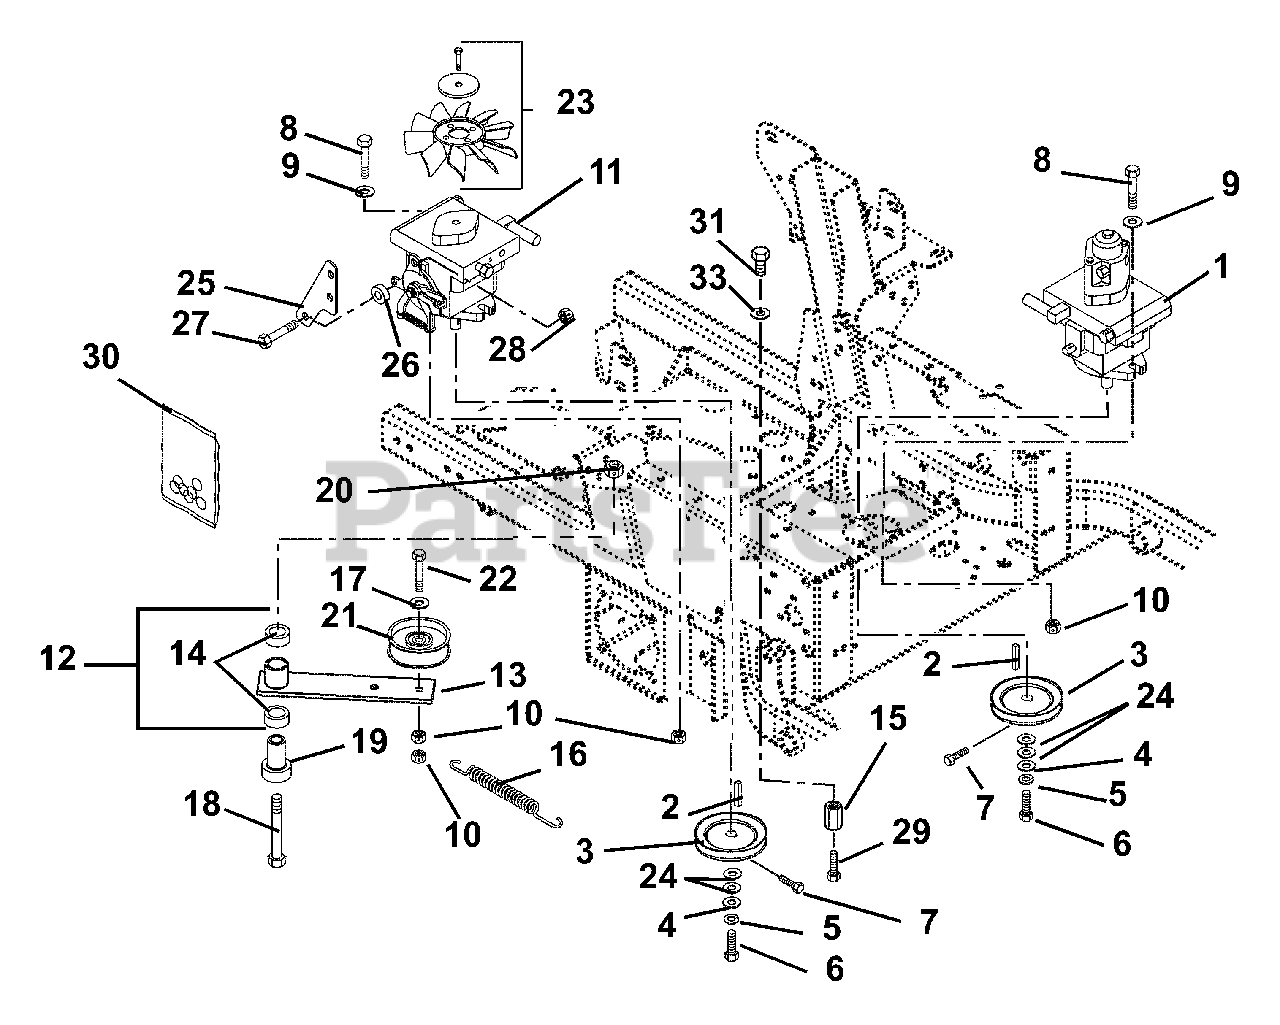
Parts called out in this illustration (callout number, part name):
1	PUMP,10CC DISP,W/AUX,W/REV RTN
2	KEY-STR 5MMX25MMX5MM
3	SHEAVE, PUMP .592 X 4.345
4	WSHR-FL-STL .281X1.000X.063
5	@WSHR-LK .25X.062 REG YWZC
6	BLT-HEX M6 X 1.0X12 YWZC
7	@BLT-HEX .25-20X.50 GR5 YWZC
8	@BLT-HEX .38-16X1.25 GR5 YWZC
9	WSHR-FL-STL .390X.75X.125 YWZC
10	@NUT-LK-TOP-FLG .38-16 YWZC
11	PUMP, BDP-10A-441 (THRU SHAFT)
12	ASSEMBLY,IDLER ARM GRD.DRIVE
13	WMT, IDLER ARM GROUND DRIVE
14	BRG, 1.00 X 1.12 X .75
15	NUT COUPLING .375-16X1.75
16	SPRING, EXTENSION
17	WSHR-FL-STL .390X.75X.125 YWZC
18	@BLT-HEX .50-13X3.50 GR5 YWZC
19	BEARING, PEDESTAL
20	@NUT-LK-TOP-FLG .50-13 YWZC
21	IDLER, FLAT 4.00X1.06
22	@BLT-HEX .38-16X2.25 GR5 YWZC
23	FAN, COOLING
24	@WSHR-FL-STL.656X1.31X.095 YWZ
25	BRACKET, RTN/DAMPER
26	SPACER .344X1.000X.375
27	@BLT-HEX .31-18X1.25 GR5 YWZC
28	@NUT-LK-TOP-FLG .31-18 YWZC
29	@BLT-HEX .38-16X1.50 GR5 YWZC
30	KIT, PUMP SEAL
31	@BLT-HEX .38-16X.75 GR5 YWZC
32	@WSHR-LK .38X.094 REG YWZC
